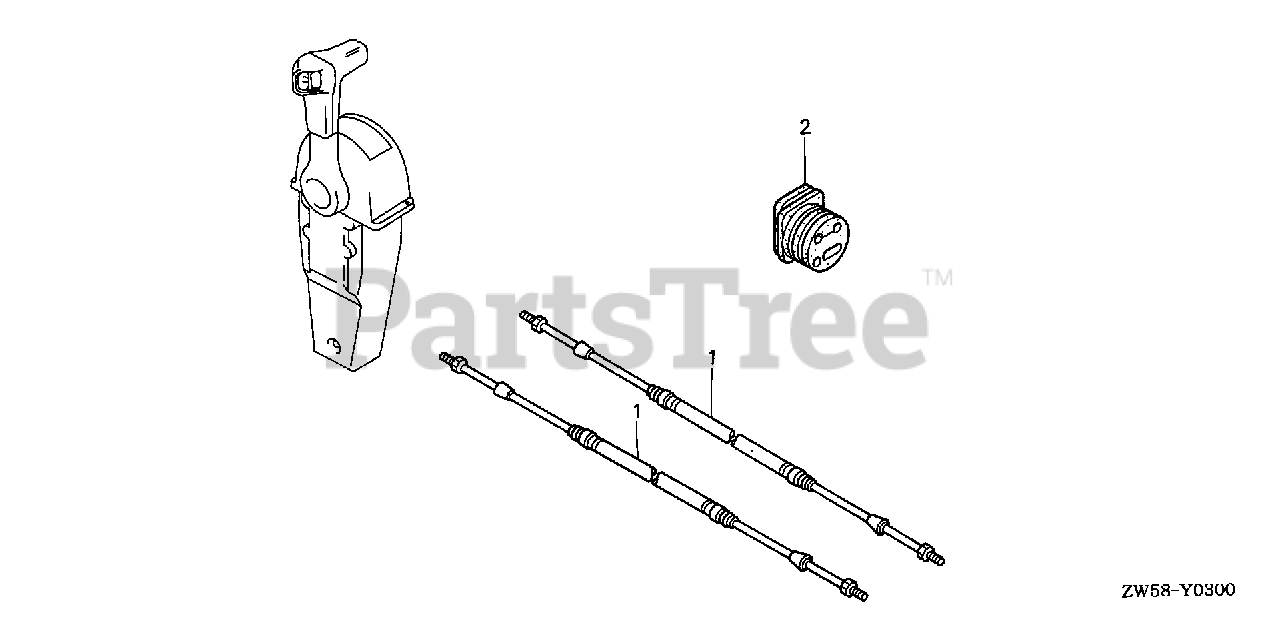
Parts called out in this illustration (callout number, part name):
1	CABLE, REMOTE CONTROL (10') (LOW FRICTION)
1	CABLE ASSY., PUSH-PULL (33C-5FT)
1	CABLE, REMOTE CONTROL (11') (LOW FRICTION)
1	CABLE ASSY., PUSH-PULL (33C-6FT)
1	CABLE, REMOTE CONTROL (12') (LOW FRICTION)
1	CABLE ASSY., PUSH-PULL (33C-7FT)
1	CABLE, REMOTE CONTROL (13') (LOW FRICTION)
1	CABLE ASSY., PUSH-PULL (33C-8FT)
1	CABLE, REMOTE CONTROL (14') (LOW FRICTION)
1	CABLE ASSY., PUSH-PULL (33C-9FT)
1	CABLE, REMOTE CONTROL (15') (LOW FRICTION)
1	CABLE ASSY., PUSH-PULL (33C-10FT)
1	CABLE, REMOTE CONTROL (16') (LOW FRICTION) (NOT AVAILABLE)
1	CABLE ASSY., PUSH-PULL (33C-11FT)
1	CABLE, REMOTE CONTROL (17') (LOW FRICTION)
1	CABLE ASSY., PUSH-PULL (33C-12FT)
1	CABLE, REMOTE CONTROL (18') (LOW FRICTION) (NOT AVAILABLE)
1	CABLE ASSY., PUSH-PULL (33C-13FT)
1	CABLE, REMOTE CONTROL (19') (LOW FRICTION)
1	CABLE ASSY., PUSH-PULL (33C-14FT)
1	CABLE, REMOTE CONTROL (20') (LOW FRICTION) (NOT AVAILABLE)
1	CABLE ASSY., PUSH-PULL (33C-15FT)
1	CABLE, REMOTE CONTROL (21') (LOW FRICTION)
1	CABLE ASSY., PUSH-PULL (33C-16FT)
1	CABLE, REMOTE CONTROL (22') (LOW FRICTION) (NOT AVAILABLE)
1	CABLE ASSY., PUSH-PULL (33C-17FT)
1	CABLE, REMOTE CONTROL (23') (LOW FRICTION)
1	CABLE ASSY., PUSH-PULL (33C-18FT)
1	CABLE, REMOTE CONTROL (24') (LOW FRICTION) (NOT AVAILABLE)
1	CABLE ASSY., PUSH-PULL (33C-19FT)
1	CABLE, REMOTE CONTROL (25') (LOW FRICTION)
1	CABLE ASSY., PUSH-PULL (33C-20FT)
1	CABLE, REMOTE CONTROL (26') (LOW FRICTION)
1	CABLE ASSY., PUSH-PULL (33C-21FT)
1	CABLE, REMOTE CONTROL (27') (LOW FRICTION)
1	CABLE ASSY., PUSH-PULL (33C-22FT)
1	CABLE, REMOTE CONTROL (28') (LOW FRICTION) (NOT AVAILABLE)
1	CABLE ASSY., PUSH-PULL (33C-23FT)
1	CABLE, REMOTE CONTROL (29') (LOW FRICTION)
1	CABLE ASSY., PUSH-PULL (33C-24FT)
1	CABLE, REMOTE CONTROL (30') (LOW FRICTION) (NOT AVAILABLE)
1	CABLE ASSY., PUSH-PULL (33C-25FT)
1	CABLE, REMOTE CONTROL (31') (LOW FRICTION)
1	CABLE ASSY., PUSH-PULL (33C-26FT)
1	CABLE, REMOTE CONTROL (32') (LOW FRICTION) (NOT AVAILABLE)
1	CABLE ASSY., PUSH-PULL (33C-27FT)
1	CABLE, REMOTE CONTROL (33') (LOW FRICTION)
1	CABLE ASSY., PUSH-PULL (33C-28FT)
1	CABLE, REMOTE CONTROL (34') (LOW FRICTION) (NOT AVAILABLE)
1	CABLE ASSY., PUSH-PULL (33C-29FT)
1	CABLE, REMOTE CONTROL (35') (LOW FRICTION)
1	CABLE ASSY., PUSH-PULL (33C-30FT)
1	CABLE ASSY., PUSH-PULL (33C-31FT)
1	CABLE ASSY., PUSH-PULL (33C-32FT)
2	GROMMET, CASE (LOWER) (B)
